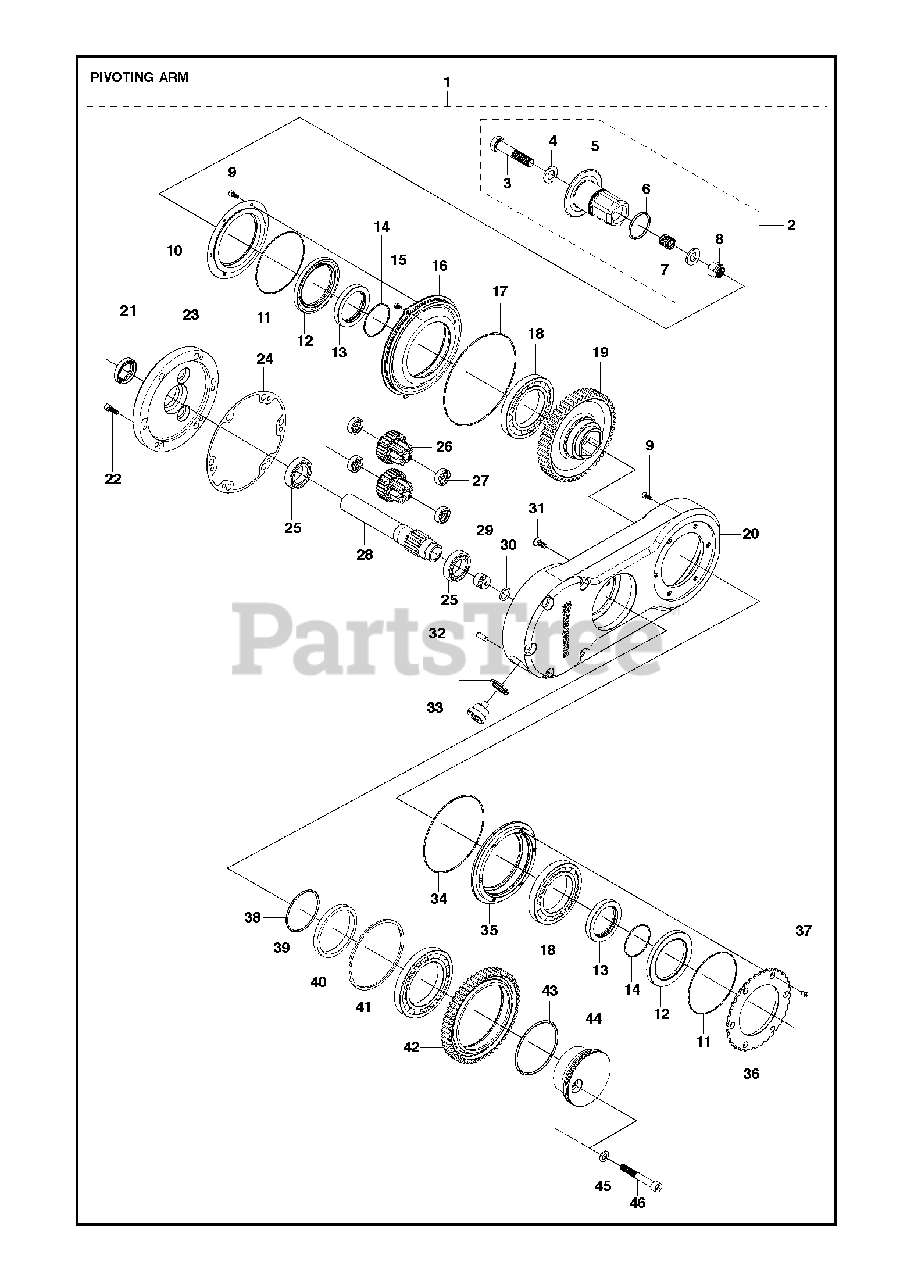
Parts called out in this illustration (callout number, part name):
1	PIVOTING ARMIncl. 2 - 44
2	SHAFT ASSYIncl. 3 - 8
45	WASHER
